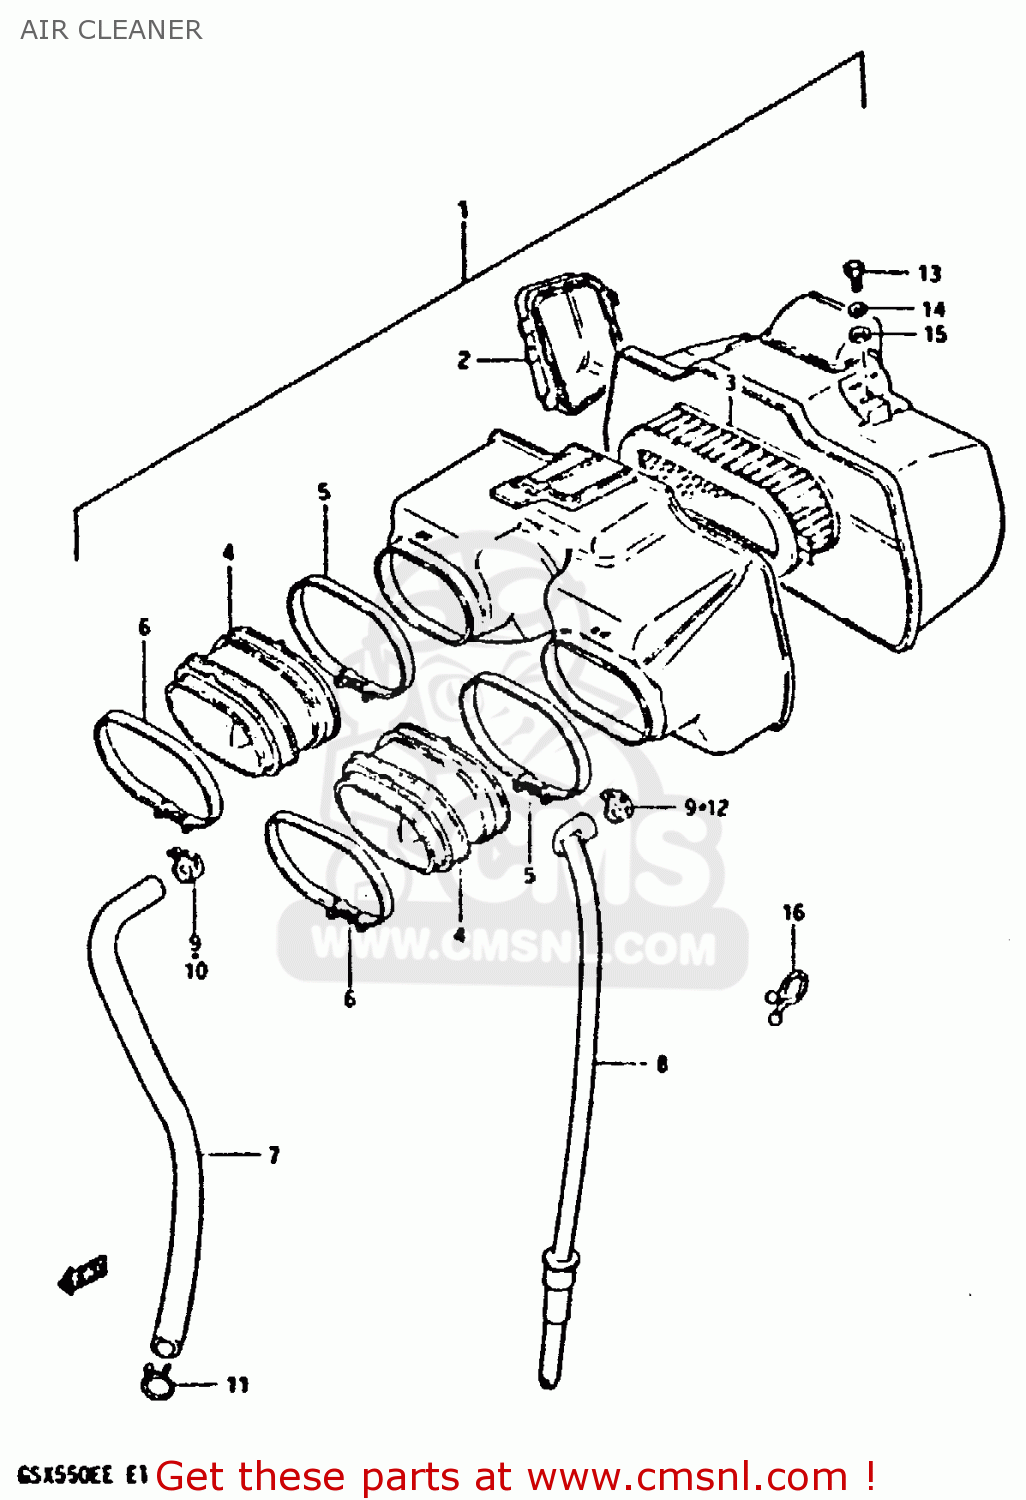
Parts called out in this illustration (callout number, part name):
1	CLEANER ASSEMBLY,AIR
2	CAP,AIR CLEANER
3	FILTER,AIR CLEANER
4	TUBE,AIR CLEANER OUTLET
5	CLAMP
6	CLAMP
7	TUBE,BREATHER
8	DRAIN TUBE
9	CLIP
10	CLIP
11	CLIP,BREATHER TUBE
12	CLIP
13	BOLT, UPPER
14	LOCK WASHER
15	WASHER
16	CLIP(ID:16)
